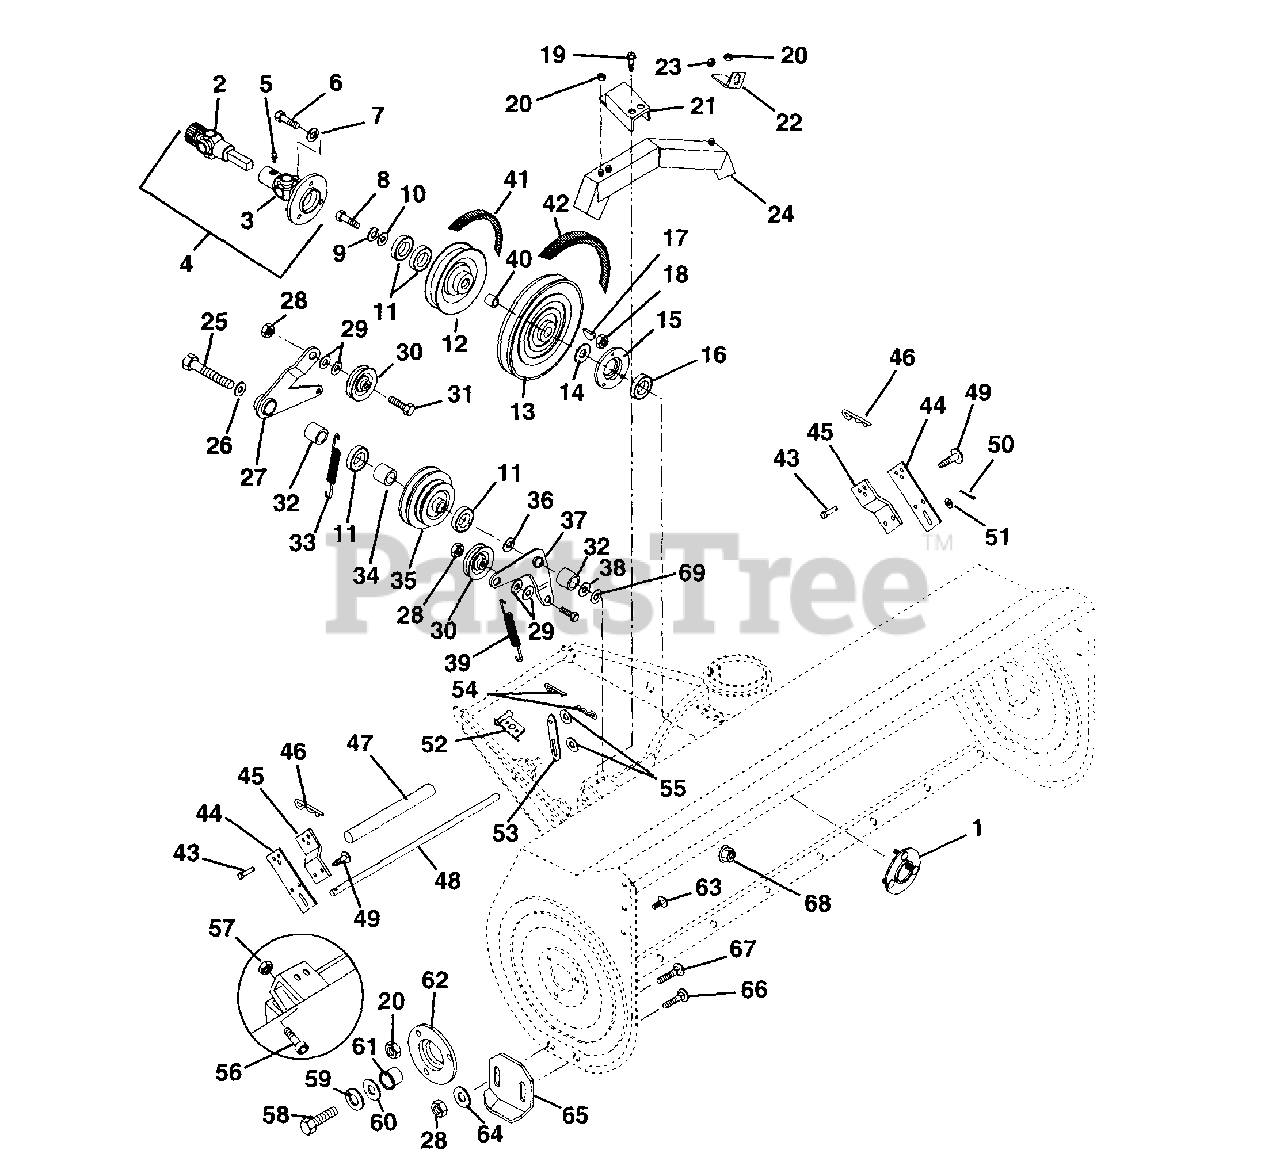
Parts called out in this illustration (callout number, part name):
1	BEARING FLANGE
2	UNIVERSAL SPLINE HALF W/ LOK
3	UNIVERSAL PLATE HALF
4	SHAFT, U-JOINT SNO HEAD
5	FTG-LUBE .25-28X.256 YWZC
6	@BLT-HEX .25-20X.75 GR5 YWZC
7	@WSHR-LK .25X.062 REG YWZC
8	@BLT-HEX .38-16X1.00 GR5 YWZC
9	@WSHR-LK .38X.094 REG YWZC
10	@WSHR-FL-STL.438X1.00X.083 YWZ
11	BRG-BALL .750X1.781X.61
13	PLY-V 10.00 X .88 W/KEY SALEM
14	WSHR-FL-STL .880X1.250X.062YWZ
15	BEARING FLANGE
16	BRG-BALL1.0X2.0X.56
17	KEY-WDRF .188X.875X.375 SAE11
18	@NUT-LK-CTR .25-20 YWZC
19	@SCR-TAP .25-20X.50 HWH TR YWZ
20	@NUT-SPNLK-FLG .25-20 YWZC
23	@NUT-LK-NYL .312-18 YWZC
24	BELT GUARD
25	@BLT-HEX .75-10X5.50 GR5 YWZC
26	WSHR-FL-STL.755X1.375X.062YWZC
27	IDLER ARM
28	@NUT-LK-CTR .38-16 YWZC
29	WSHR-FL-STL .406X.875X.135
30	IDLER-FLAT 3.00 X .38 CLK.&CAP
31	@BLT-HEX .38-16X1.25 GR5 YWZC
32	BSHG-SLV .750X1.125X1.062
33	SG-TENS .109X1.00X6.0
34	SPACER .781X1.000X.547
36	@WSHR-FL-STL.812X1.50X.135YWZC
37	IDLER ARM
38	WSHR-HDND-THRST .755X1.40X.062
39	SG-TENS .109X1.00X6.0
40	SPACER .906X1.125X.453
41	V-BELT, HA-RAW EDGE
42	V-BELT, 4L-RAW EDGE
43	PIN-CLEV .50X1.25 RH ST PL
44	LIFT LINK
45	SUPPORT
46	PIN-HAIR INT .08X.18X1.18 YWZC
47	TUBE .725 X .875 X 14.00
49	@SCR-TAP .31-18X.50 HWH TR YWZ
50	@PIN-CTR .12X1.25 EXTPRSQCT YZ
51	@WSHR-FL-STL.688X1.75X.134 YWZ
52	LIMITING POST
53	LIMITING ARM
54	HAIRPIN, #7 CLIP .094X2.31 YWZ
55	@WSHR-FL-STL.531X1.06X.095YWZC
56	SCR-SKH 10-24X.38
57	NUT-LK-DUAL FACE 10-24 YWZC
58	@BLT-HEX .50-13X1.00 GR5 YWZC
59	WSHR-LK .500X.151 HVY YWZC
60	WSHR-FL-STL.511X1.441X.125 YWZ
61	BSHG-FLG 1.000X1.12X.62X1.50BR
62	BEARING SUPPORT
63	BLT-SERNK SL .25-20X.50 YWZC
64	@WSHR-FL-STL.38X.875X.083 YWZC
65	RUNNER, SKID SHOE-1/2" FLANGE
66	BLT-RHHDSQSHNK .38-16X.75 G2YZ
67	@BLT-RDHDSQNK .38-16X1.00 G5YZ
68	@NUT-LK-CTR .75-10 YWZC
69	WSHR-FL-STL.755X1.375X.062YWZC
